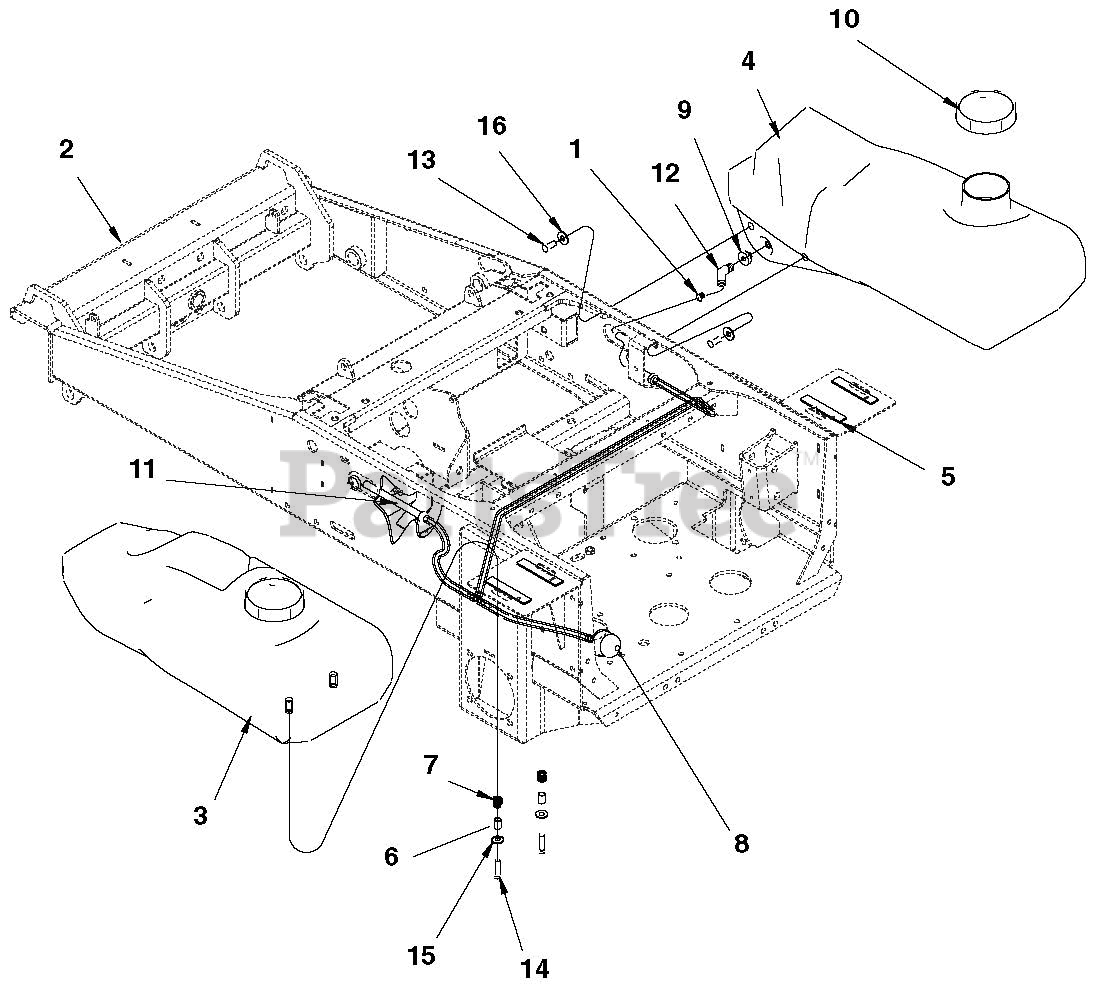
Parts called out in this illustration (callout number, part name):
1	CLAMP, HOSE - 1/2" SPRING
2	FRAME WITH DECALS ACM
3	TANK, LH MIDMOUNT BLANK W/CAP
4	TANK, RH MIDMOUNT BLANK W/CAP
5	FOAM, .125 X .750 X 4.00
6	SPACER, GAS TANK ATTACHMENT
7	SPRING, COM .660 X .067 X .625
8	FUEL FILTER - KAWASAKI
9	GROMMET, RUBBER TANK S/O
10	CAP, FUEL S/O
11	ASSY, FUEL LINE W/CHECKVALVES
12	FTG, 90 1/4HOSE X 1/2HOSE S/O
13	BOLT, 3/8-16X.750 HEX 5 Y
14	BOLT, 3/8-16X1.25 HEX 5 Y
15	WASHER, .313 REG FLAT Y
16	WASHER, .375 REG FLAT Y
